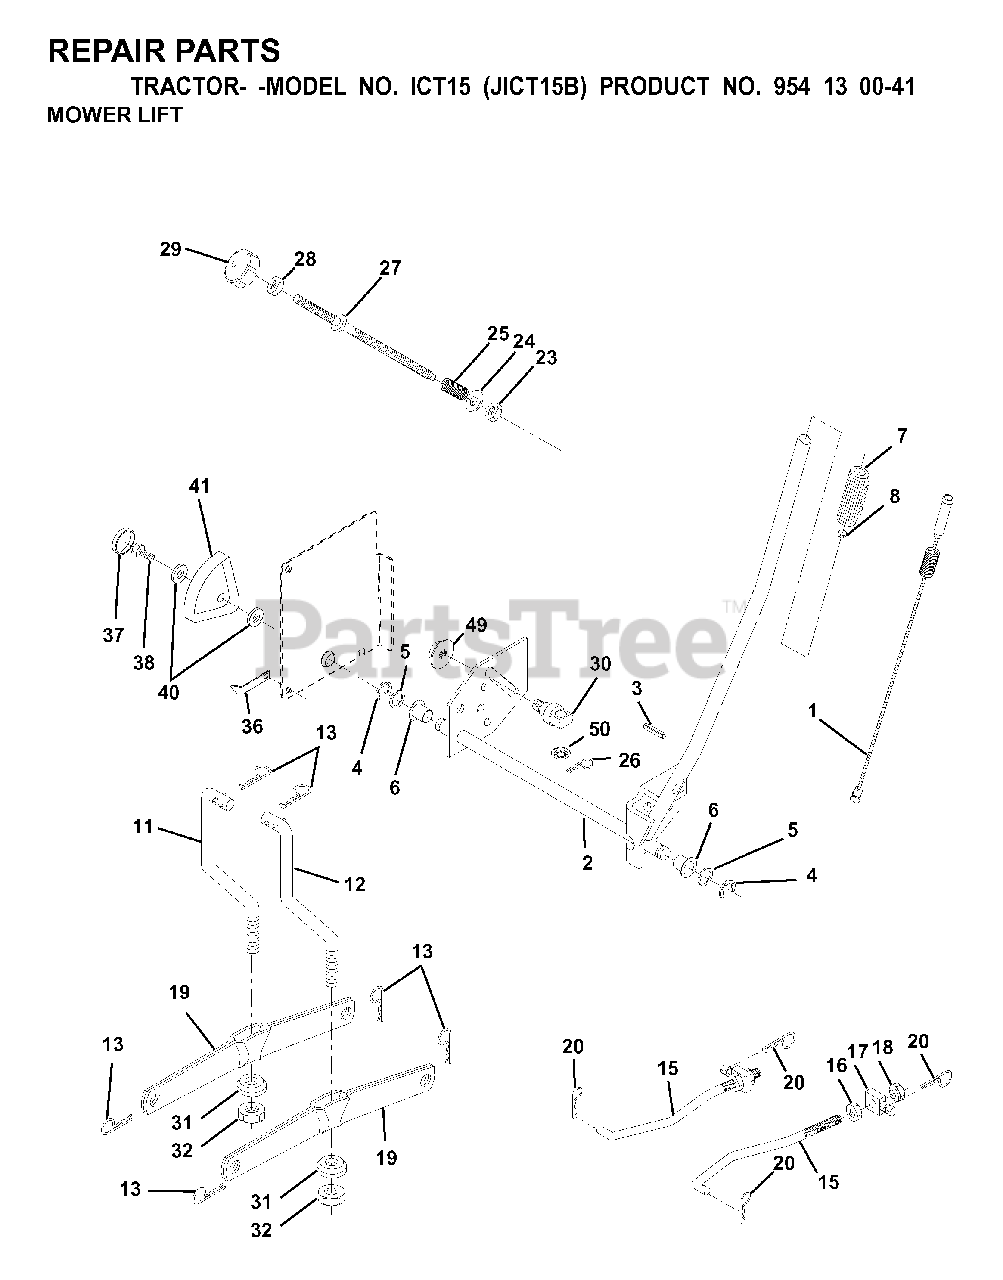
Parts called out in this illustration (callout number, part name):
1	WIRE ASM INNER W/ PLUNGER LT
2	SHAFT ASM R HANDLE
3	PIN GROOVE
4	RETAINING RING LT
6	BEARING.NYLON
7	GRIP HANDLE
8	PLUNGER BUT KIT
11	LINK
12	LINK
13	RETAINER-SPRNG RB
15	LINK FRONT
16	NUT
17	TRUNION
18	NUT
19	ARM.REAR.SUSPENSION
20	SPRING RETAINER
25	SPRING**
26	RETAINER CLIP
27	ROD ADJ LIFT
28	NUT
29	KNOB INF 3/8-16
31	BEARING PIVOT
32	NUT CROWNLOCK 3/8-24
36	POINTER, HEIGHT INDICATOR
37	PLUG,HOLE
38	SCREW 5/16-18X1
41	HEIGHT INDICATOR
49	NUT
50	NUT PUSH M
